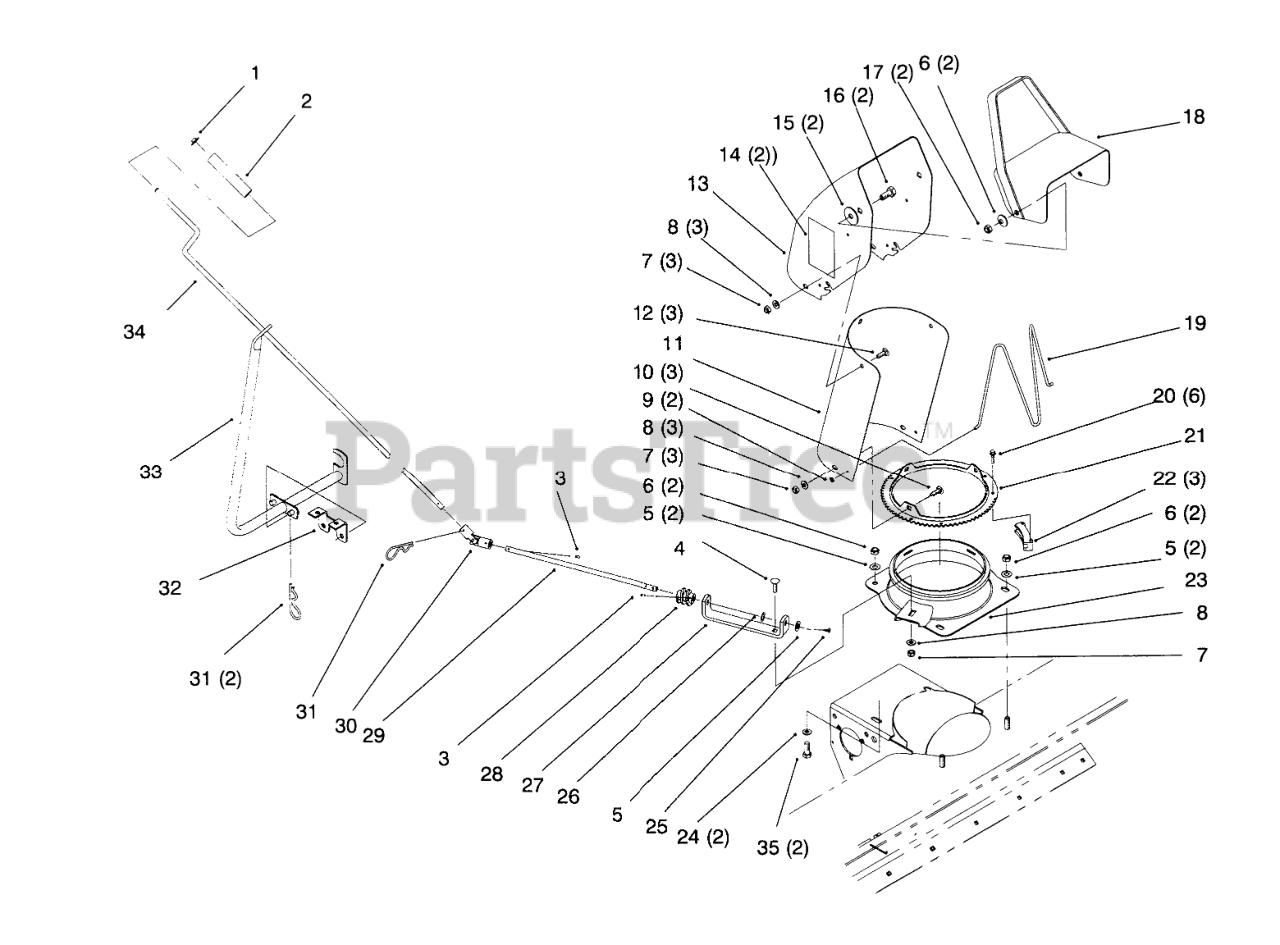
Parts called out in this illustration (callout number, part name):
1	RETAINER-PUSH ON
2	GRIP-CONTROL, CHUTE
3	PIN-SPRING
4	BOLT-CARR
5	WASHER-FLAT
6	NUT-LOCK, NI
7	NUT-LOCK, NI
8	WASHER-PLAIN
9	NUT-PUSH
10	BOLT-CARR
11	EXTENDER-CHUTE, UPPER
12	SCREW-HH
13	DISCHGE CHTE/DECAL ASM R
14	Decal-Danger
15	WASHER-RUBBER
16	BOLT-CARR
17	WASHER-BELLEVILLE
18	DEFLECTOR
19	WIRE-CHUTE
20	SCREW-SPECIAL
21	CHUTE SWIVEL RING
22	RETAINER-CHUTE
23	ADAPTER
24	WASHER-SPACER
25	PIN-COTTER
26	WASHER-SPRING
27	BRACKET-WORM
28	GEAR-WORM, CHUTE
30	Universal
31	PIN-HAIR
32	BRACKET
33	SUPPORT
34	ROD-CHUTE CONTROL
35	SCREW-HH
